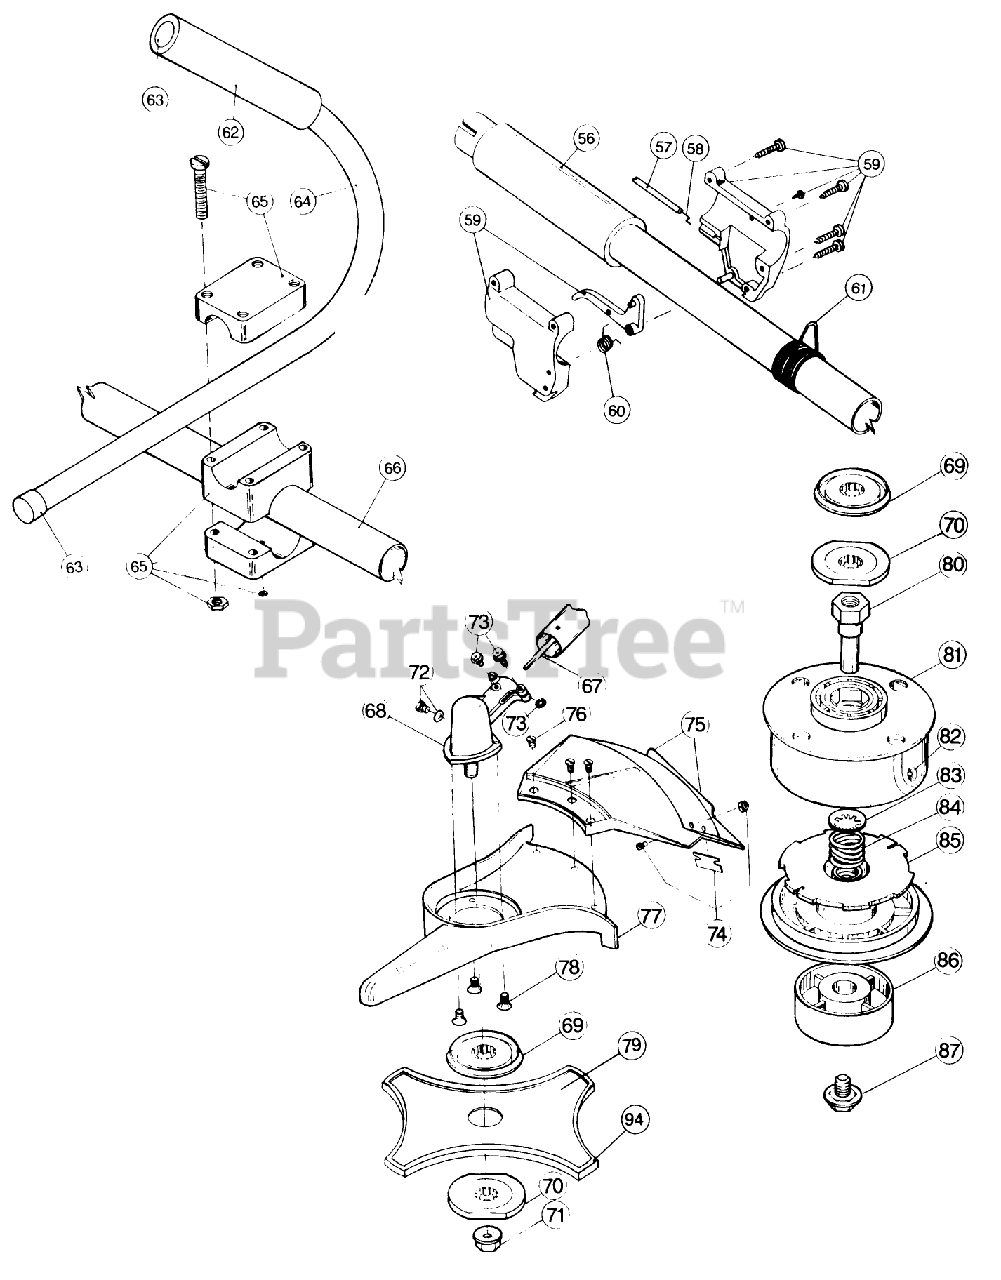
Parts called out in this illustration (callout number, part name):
58	THROTTLE CABLE WIRE
60	THROTTLE TRIGGER SPRING
62	HANDLE NITRILE GRIP
63	TUBE CLOSURE
65	HANDLE BRACKET ASM
66	DRIVE SHAFT HSG ASM
68	GEAR BOX ASM
74	BLADE ASM
75	GUARD & BLADE ASM
76	GUARD MNTG SCREW ASM
77	Guard
81	OUTER SPOOL EYELET ASM
82	EYELET
83	RETAINER
84	SPRING
88	STRAP SHOULDER ACC
94	BLADE SAFETY GUARD
